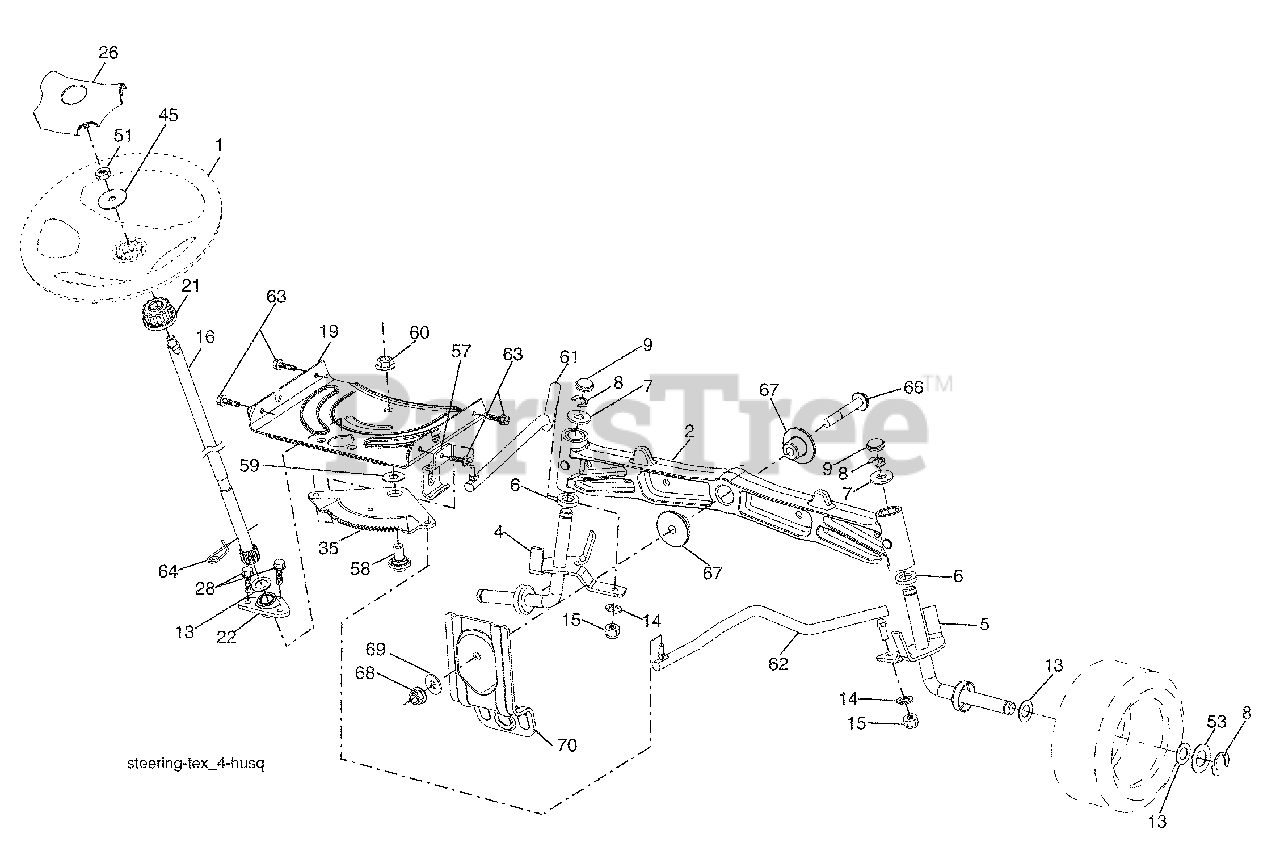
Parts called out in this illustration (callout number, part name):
1	Wheel, Steering
2	Axle Asm., Front
4	Spindle Asm., LH
5	Spindle Asm., RH
6	Bearing, Race Thrust Harden
7	Washer 25/32 x 1-5/8 x 16 Ga.
8	Ring, Clip #T5304-75
9	Cap, Spindle
13	Washer 25/32 x 1-1/4 x 16 Ga.
14	Washer, Lock Hvy Hlcl Spr 3/8
15	Nut, Crown Lock 3/8-24 unf
16	Shaft Steering
19	Plate Steering
21	Adapter, Wheel Steering
22	Bushing, Strg. Blk
26	Insert, Wheel Steering
28	Screw 3/8-16 x 3/4
35	Gear, Sector Plate
45	Washer 9/16 x 2-3/8 x 12 Ga.
51	Nut Hex Jam Toplock 1/2-20 unf
53	Washer Hardened .793 x 1.637 x .060
57	Bracket Upstop
58	Bolt Shoulder Sector Pivot CFM
59	Washer Thrust Sector Steering
60	Nut Flange Lock 5/8-11
61	Draglink, LH
62	Draglink, RH
63	Screw 5/16-18 x 3/4
64	Retainer Clip Spring Steering
66	Bolt Hex Fghd 7/16-14 x 3 Serr
67	Bushing PM Front Axle
68	Nut Lock Flange 7/16-14 Gr. 5
69	Washer 1.5 x .505 x .118
70	Bracket Deck Susp. Front
